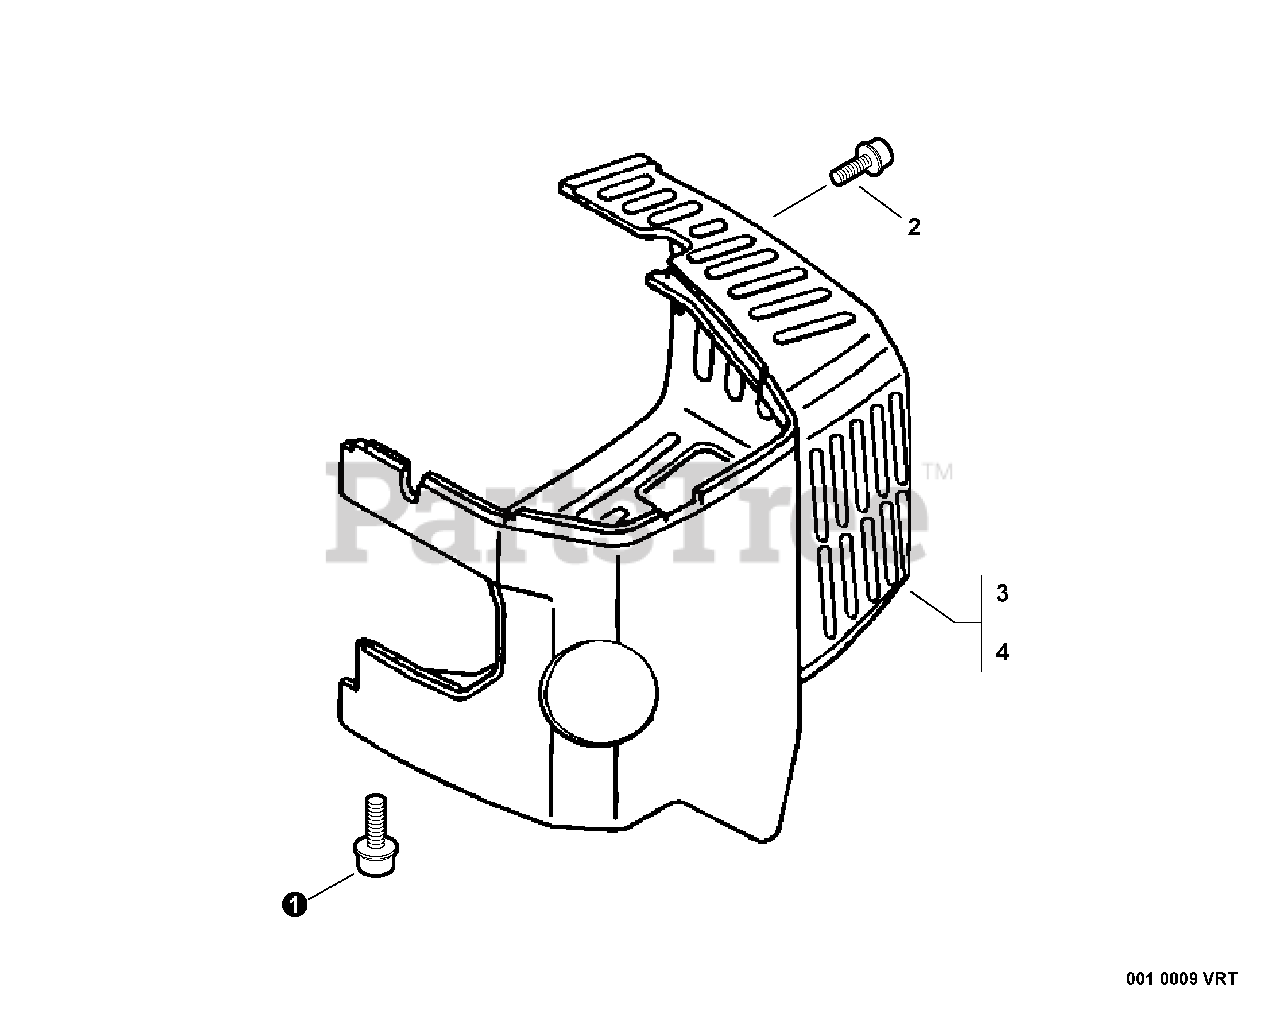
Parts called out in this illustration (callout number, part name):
1	BOLT 4×20
2	BOLT 4×8
3	COVER, ENGINE
4	COVER, ENGINE
